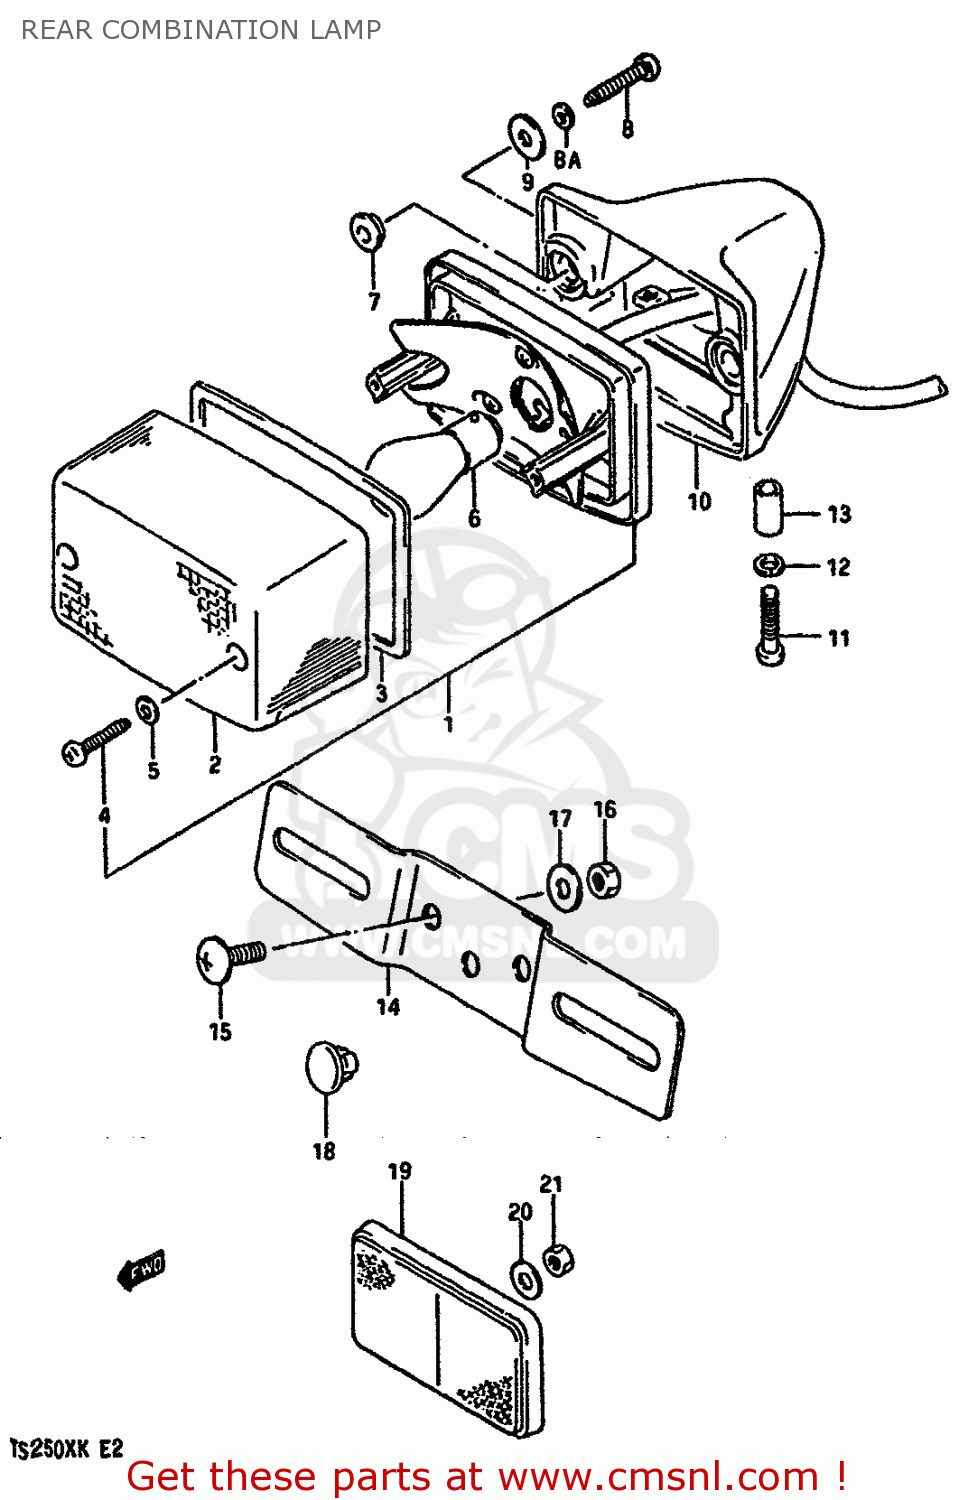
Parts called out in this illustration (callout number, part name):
1	LAMP UNIT,REAR COMBINATION
2	LENS
3	GASKET,RR COMBI LAMP LENS (NAS)
4	SCREW
5	GASKET (NAS)
6	BULB(12V21/5W)
7	SPACER,RR COMBI
8	SCREW
8A	WASHER,LOCK
9	WASHER
10	BRACKET UNIT,TAIL LAMP
11	SCREW
12	WASHER,LOCK
13	SPACER(6.4X9.2X12)
14	PLATE,RR LICENSE
15	SCREW
16	NUT
17	WASHER
18	CUSHION
19	REFLEX REFLECTOR,RR
20	WASHER
21	NUT
